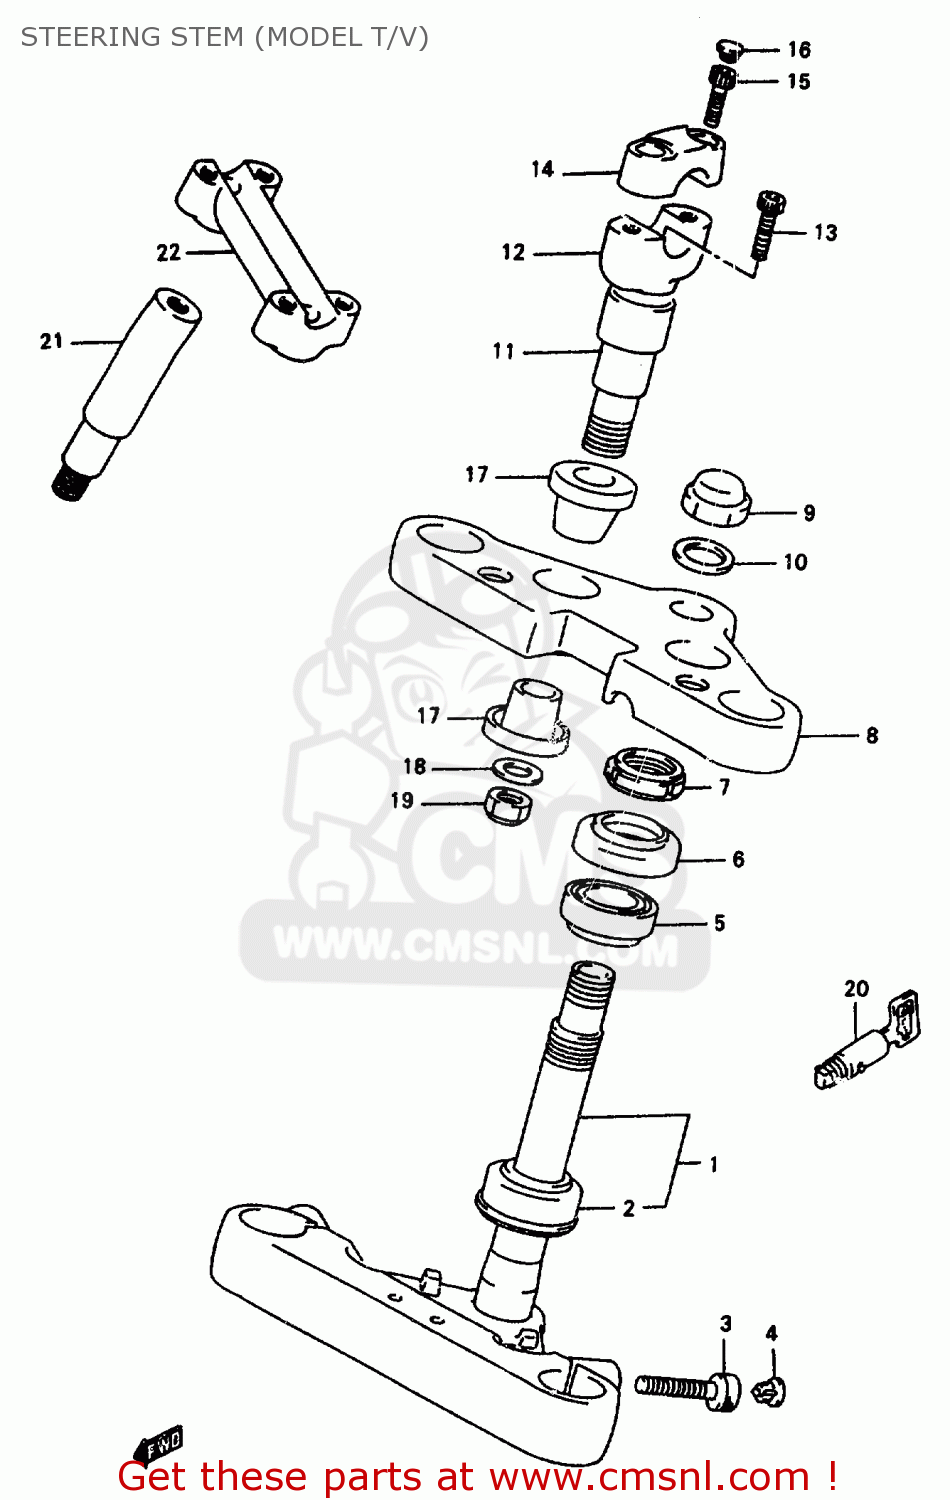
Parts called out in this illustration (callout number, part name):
1	STEM,STEERING
2	BEARING(30X55X17)
3	BOLT
4	CAP(OD:12)
5	BEARING(25X47X15)
6	SEAL,STEERING UPR DUST
7	NUT,STEERING STEM(25X44X10)
8	BRACKET,UPR
9	NUT,CAP
10	WASHER(22.5X32X1.6)
11	STAY,HANDLE
12	HOLDER,HANDLE LWR
13	BOLT
14	HOLDER,HANDLE UPR
15	BOLT
16	CAP(OD:14.5)
17	DAMPER,RUBBER
18	WASHER
19	NUT
20	LOCK SET,STEERING
21	STAY,HANDLE
22	HOLDER,HANDLE LWR
